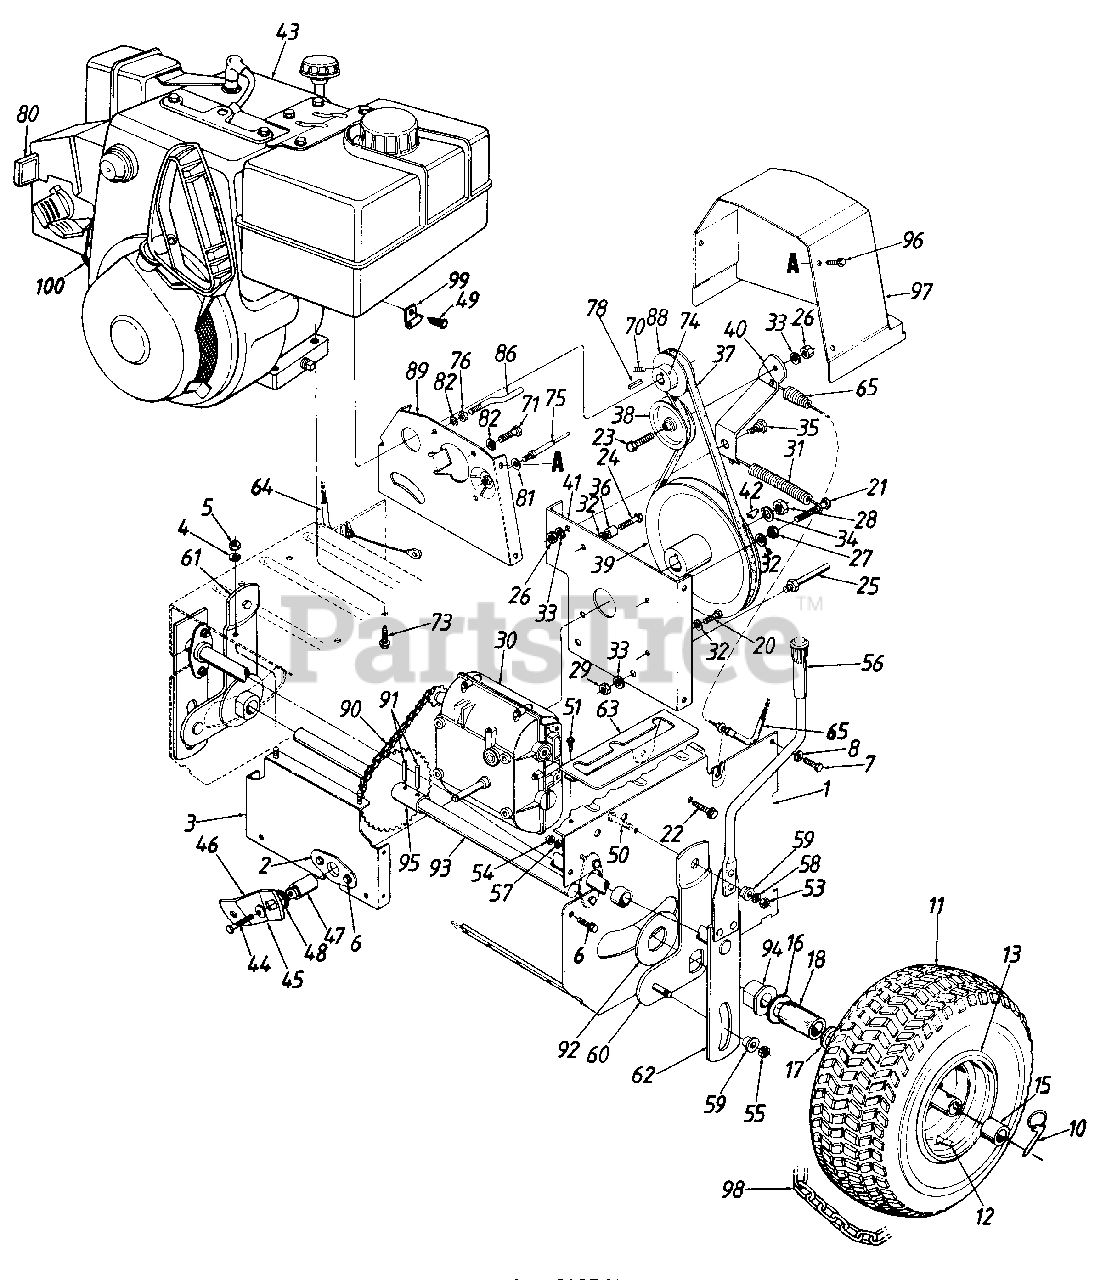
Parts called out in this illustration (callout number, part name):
1	Frame Ass'y.
2	Shift Support
3	Back Plate Ass'y.
4	L-Wash. 1/4" I.D.
5	Hex Nut 1/4-20 Thd.
6	Hex TT-Tap Scr. 1/4-20 x .5" Lg.
7	Hex Self-Tap Scr. 3/8-16 x .75" Lg.
8	L-Wash. 3/8" I.D.
10	Kwick Pin
11	Wheel Ass'y. Comp.
13	Rim Only
15	Sleeve Brg. .755" I.D.
16	Fl-Wash. .793" I.D.
17	Fl-Wash. .75" I.D.
18	Spacer.75" I.D.
20	Hex Bolt 5/16-18 x .75" Lg.*
21	Hex Bolt 5/16-18 x 1.5" Lg.
22	Hex Wash. Hd. B-Tap Scr. 5/16-18 x .5" Lg.
23	Hex Bolt 3/8-24 x 1.5" Lg.
24	Hex Bolt 5/16-18 x 1.25" Lg.
25	Stud 3/8-16 x 2.75" Lg.
26	Hex Nut 3/8-24 Thd.
27	Hex Nut 5/16-18 Thd.
28	Nut 1/2-20 Thd.
29	Hex Jam Nut 3/8-16 Thd.
30	Transmission Comp.
31	Extension Spring 3.97" Lg.
32	L-Wash. 5/16" I.D.
33	L-Wash. 3/8" I.D.
34	L-Wash. 1/2" I.D.
35	Shld. Bolt 1/2" Dia. x .175"
36	Spacer.315" I.D.
37	V-Belt
38	Flat Idler 1.88" Dia.
39	Trans. Pulley 7" O.D. x 3L
40	Trans. Idler Arm
41	Trans. Support Plate
42	Key
43	Engine ??
44	Hex Bolt 1/4-28 x 1.75" Lg.
45	Bell-Wash. 1/4" I.D.
46	Shift Arm
47	Shift Arm Extension
48	Fl-Wash. .63" I.D. x .93" O.D.
49	Hex Bolt 1/4-20 x .5" Lg.
50	Hex Bolt 3/8-24 x 1" Lg.
51	Hex Wash. Hd. B-Tap Scr. 5/16-18 x .5"
53	Hex Nut 3/8-24 Thd.
54	Hex Nut 5/16-18 Thd.
55	Hex L-Nut 3/8-24 Thd. Gr. 5
57	L-Wash. 5/16" I.D.
58	L-Wash. 3/8" I.D.
59	Shoulder Spacer
60	Side Arm Ass'y.-R.H.
61	Side Arm Ass'y.-L.H.
62	Pivot Handle Ass'y.
63	Position Selector Plate
64	Clutch Cable 25.5" Lg.
65	Auger Cable 25.5" Lg.
70	Set Scr. 1/4-28 x .18"
71	Hex Bolt 5/16-24 x .62"
73	Hex L-Wash. TT-Tap Scr. 3/8-16
74	Set Scr. 1/4-28 x .25"
75	Stud 3/8-16 x 3.37" Lg.
76	Hex Nut 5/16-24 Thd.
78	Key 8/32" x 5/8" Dia.
80	Plastic Key-Craftsman
81	Bell-Wash. 88" I.D. x .88"
82	L-Wash. 5/16" I.D.
86	Belt Guard Scr.
88	Auxiliary PTO Pulley
89	Engine Plate Ass'y.
90	Chain #420 1/2 Pitch x 41 Links
91	Spring Spiral Pin
92	Slide Washer
93	Free Wheeling Axle
94	Flange Brg. w/Flats .752 I.D.
95	30 T-Sprocket Hub Ass'y.
96	Hex B-Tap Scr. 5/16-18 x .5 Lg.
97	Belt Cover
98	Tire Chains
99	Clamp
100	Cable Tie
